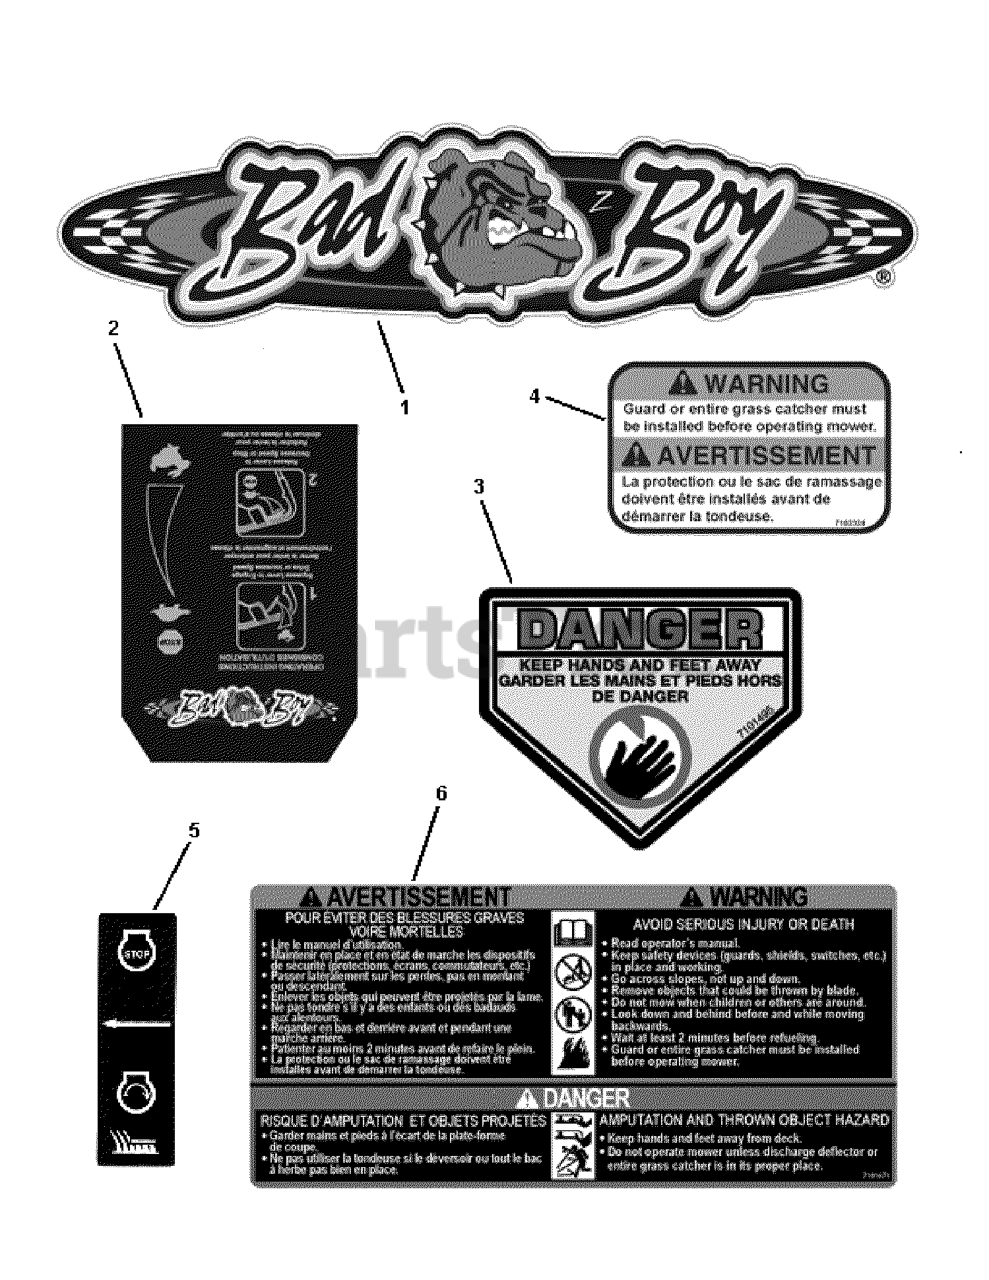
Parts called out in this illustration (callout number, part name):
1	DECAL, Bad-Boy LG
2	DECAL, Controls Bad-Boy
3	DECAL, CPSC, French/English
4	DECAL, Chute/Deflector FC
5	DECAL, OPC Bail International Symbol
6	DECAL, French/English, WB Safety
